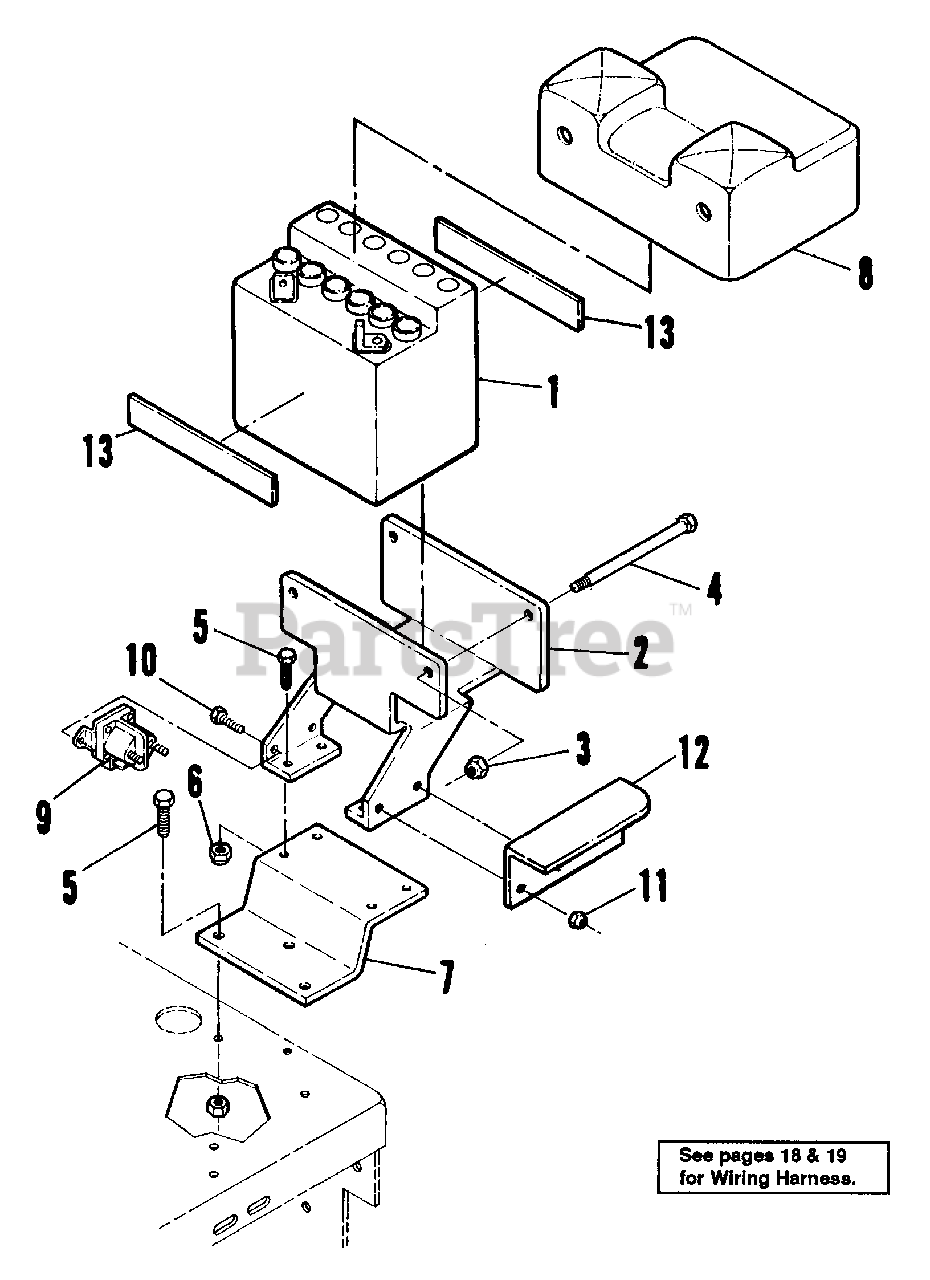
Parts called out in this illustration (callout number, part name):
1	BATTERY, 12 Volt
2	BOX, Battery
3	NUT, 1/4"-20 Hex Nylon Lock
4	SCREW, 1/4"-20 x 5 3/4" Lg. Hex Head Cap
5	SCREW, 5/16"-18 x 3/4" Lg.
6	NUT, 5/16"-18 Hex Lock
7	BRACKET, Battery Mount
8	COVER, Battery
9	SOLENOID, 12V LT
10	SCREW, 1/4"-20 x 5/8" Lg. Hex Head Cap
11	NUT, 1/4"-20 Hex Nylon Lock
12	SHIELD, Heat (18 HP Kohler)
13	STRIP, Rubber
